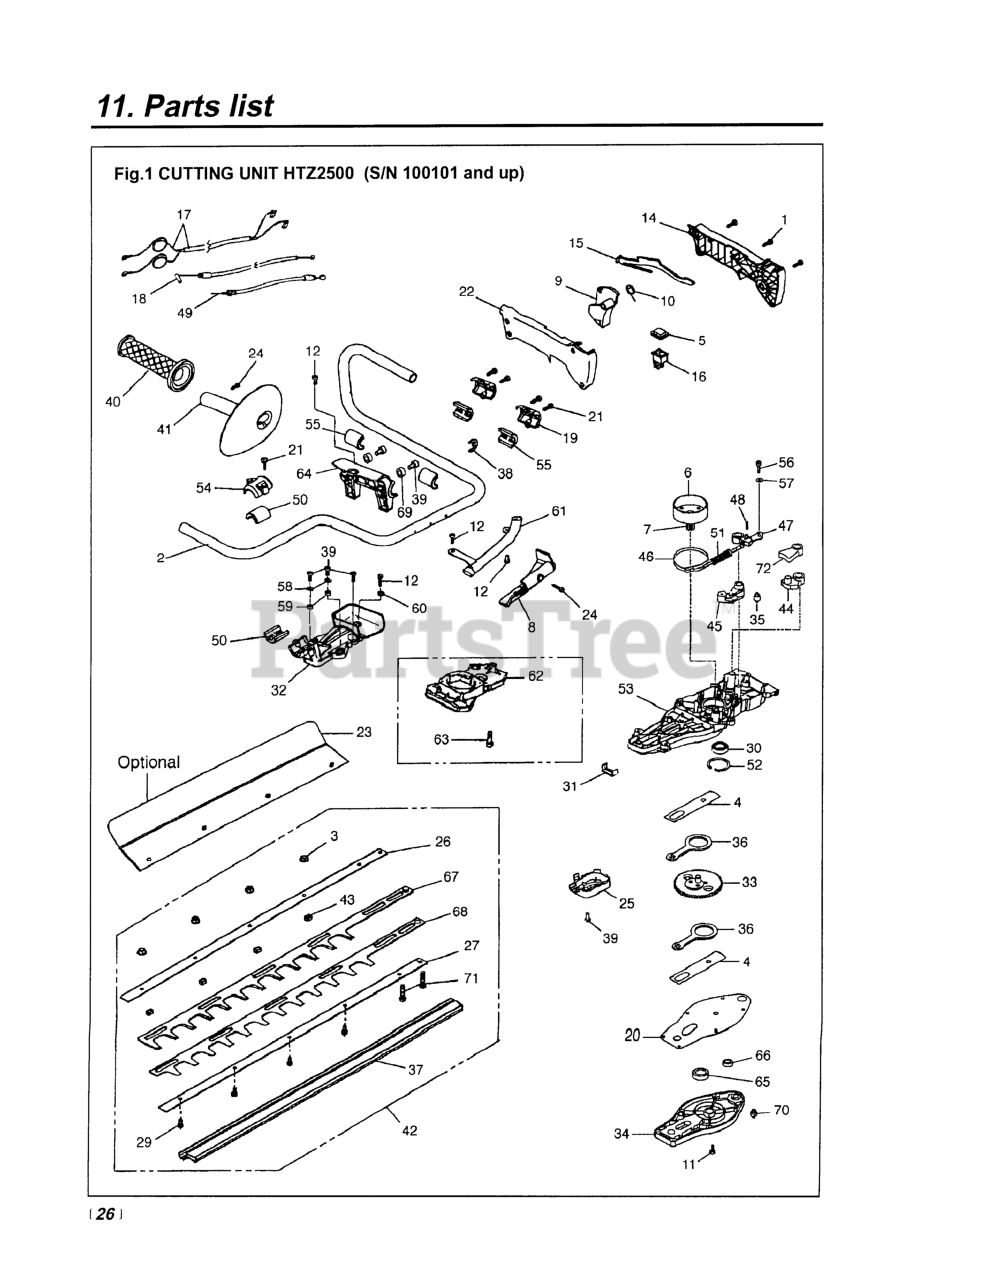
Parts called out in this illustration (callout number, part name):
1	SCREW (HANDLE)
3	NUT
4	PLATE
5	GUARD, SWITCH
6	DRUM, CLUTCH
7	GEAR, DRIVE (USE T4500-13110)
8	GUARD (RPLS 58040206A)
9	LEVER, THROTTLE
10	SPRING
11	SCREW TORX, M5X22
12	SCREW
15	LEVER
16	SWITCH (RPLS 2317011A)
17	CABLE
18	CABLE, THROTTLE
20	GASKET
21	SCREW (HANDLE)
23	DEFLECTOR
26	SUPPORT, UPPER
27	SUPPORT, LOWER
29	SCREW
30	BEARING
32	SUPPORT
34	COVER
35	ROLLER
37	GUARD, BLADE
39	SCREW
42	BLADE ASSY (RPLS 58040094)
43	SPACER
44	CAM, BRAKE
45	LEVER
46	BAND, BRAKE
47	LEVER, BAND
48	PIN
49	CABLE, THROTTLE
51	SPRING
52	RING, SNAP
53	CASE, GEAR (RPLS 58042021)
56	SCREW
57	WASHER
60	BUSHING
61	DEFLECTOR
62	COVER, GEAR
63	SCREW TORX, M5X22
64	SUPPORT
65	BEARING
66	BEARING
67	BLADE, UPPER
68	BLADE, LOWER
70	GREASE NIPPLE
71	SCREW (BLADE)
72	LEVER
